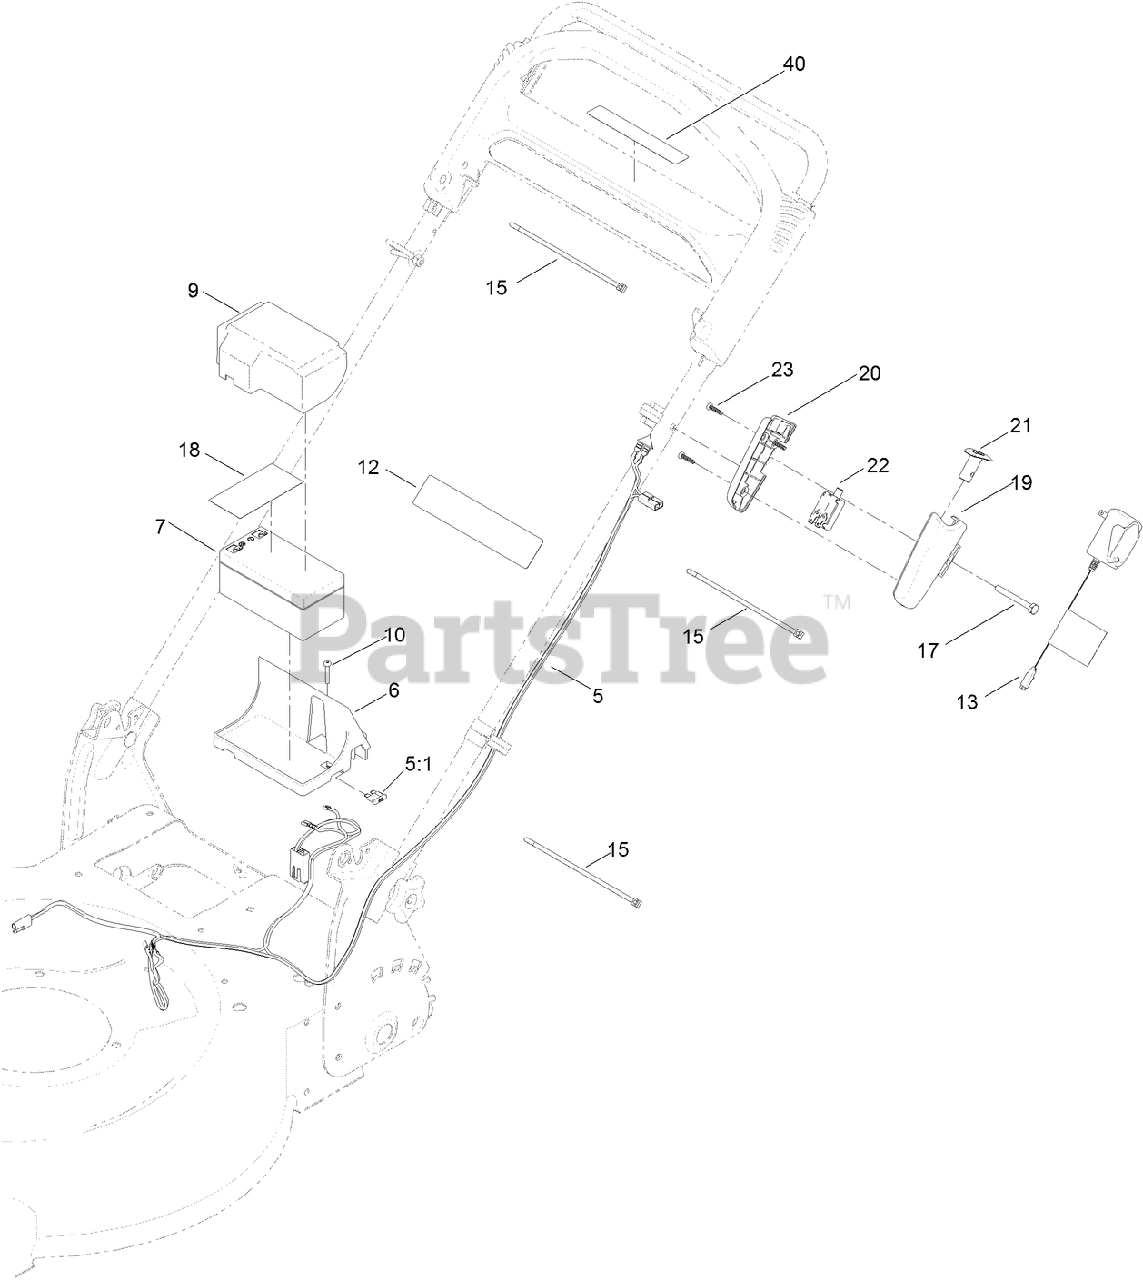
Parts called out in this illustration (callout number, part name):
5	HARNESS-WIRE
5:1	FUSE-40 AMP
6	TRAY-BATTERY
7	BATTERY-WET
9	COVER-BATTERY
10	SCREW-PPH, PLASTITE
12	DECAL-WARNING
15	TIE-CABLE
17	SCREW-HH
18	DECAL-TERMINAL, BATTERY
21	BUTTON-SWITCH
22	SWITCH-PUSH BUTTON
23	SCREW-PPH
40	DECAL-BUTTON, PUSH
